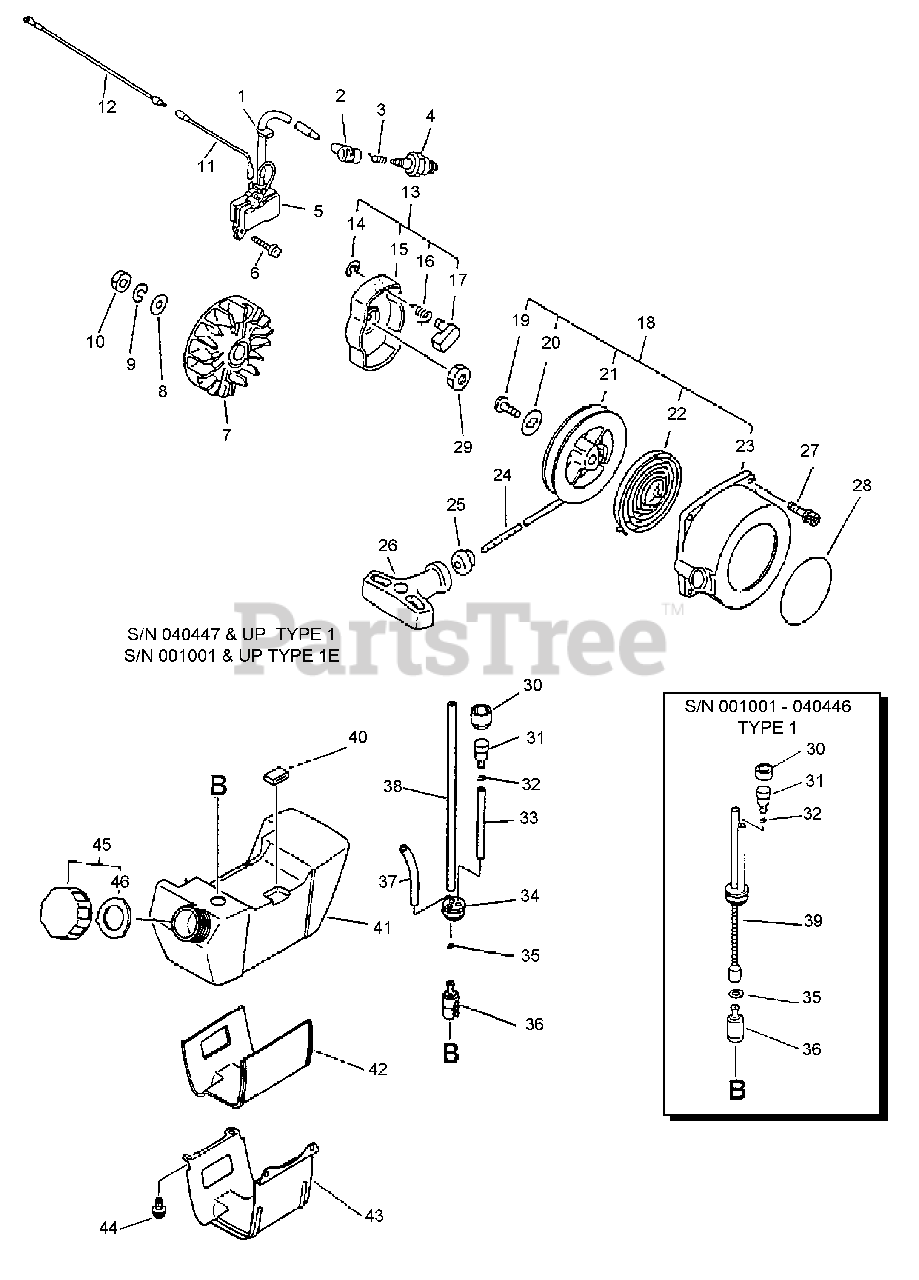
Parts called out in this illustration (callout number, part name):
2	CAP, SPARK PLUG
3	TERMINAL, SPARK PLUG
4	SPARK PLUG - BPM7A
5	COIL, IGNITION
6	BOLT 5×20
7	FLYWHEEL
8	WASHER 10.5×18×1.6
9	WASHER, SPRING 10
10	NUT 10×1.25
12	LEAD - GROUND
13	PAWL ASSY, STARTER
14	E-RING 4
15	PAWL CATCHER
16	SPRING, RETURN
17	PAWL, STARTER
18	STARTER ASSY
21	REEL, ROPE
22	SPRING, RECOIL
23	CASE, STARTER - ORANGE
25	GUIDE, ROPE
26	GRIP, STARTER
27	BOLT 4×20
28	LABEL, ECHO
29	NUT 8×1.25
30	HOLDER, VENT
31	VENT ASSY
33	PIPE, FUEL VENT 3×5×60
34	GROMMET, FUEL
35	WASHER 5.5×12×0.8
35	CLIP 6 MM
36	FILTER, FUEL
37	PIPE, FUEL RETURN 3×6×90 MM CLEAR
38	PIPE, FUEL 3x-5x-180
39	PIPE, FUEL
41	TANK, FUEL
43	BRACKET, FUEL TANK
44	SCREW 5×14
45	CAP ASSY, FUEL
46	GASKET, FUEL CAP
